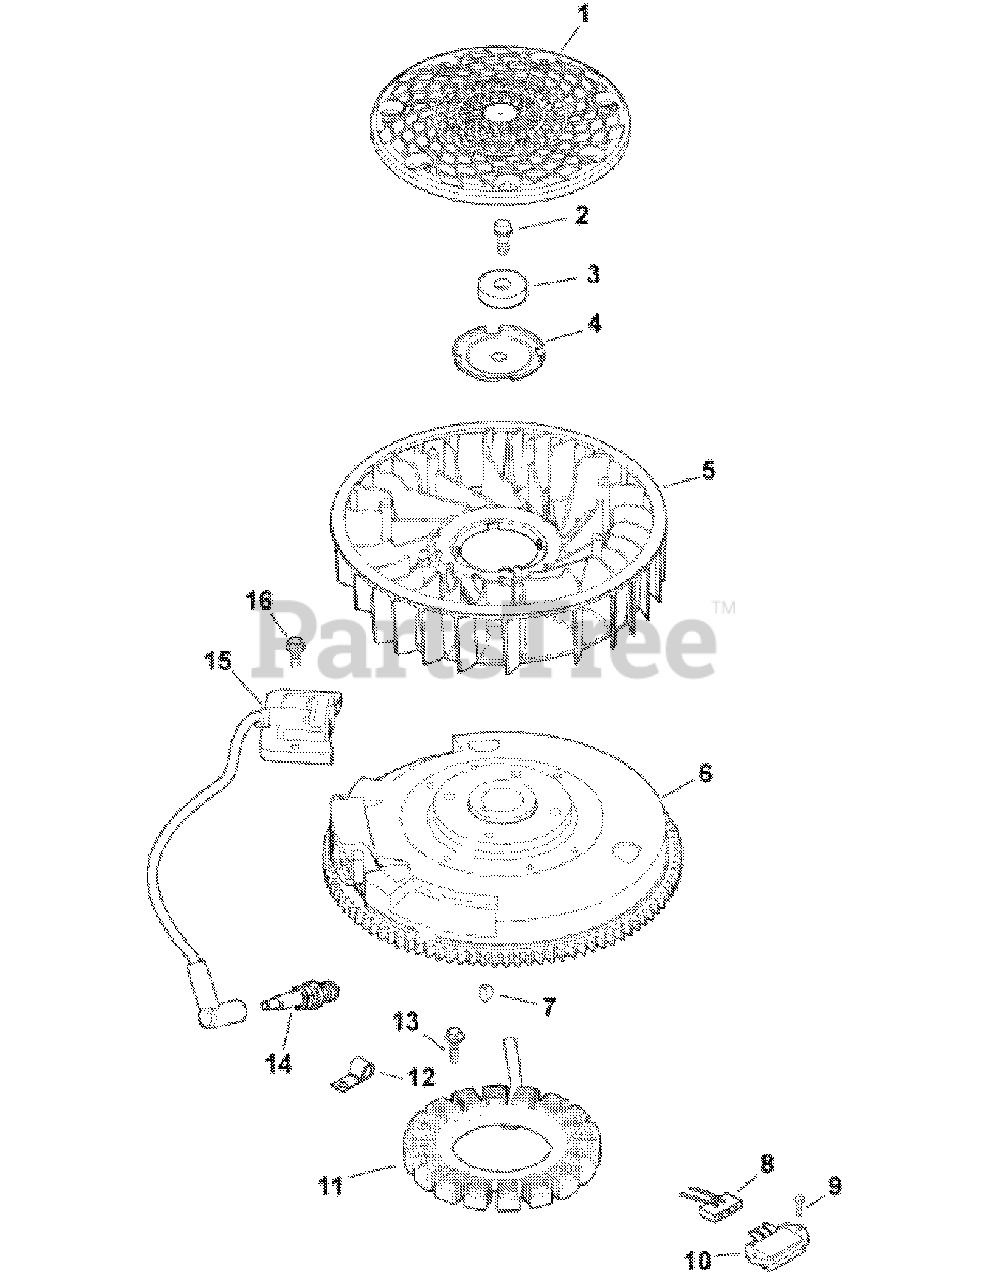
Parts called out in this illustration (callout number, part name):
2	SCREW, FLG M10X1.5X45
3	WASHER, FLAT 13/32"
5	FAN
6	FLYWHEEL
7	KEY, 3/16" X 5/8"
8	CONNECTOR (3 CONTACT)
9	SCREW, HVY FLG M5X.8X16
10	RECTIFIER-REGULATOR
11	KIT, 15 AMP STATOR
13	SCREW, THD FRM M5X.8X25
14	PLUG, SPARK
16	SCREW, FLG THD FRM M5X.8X20
